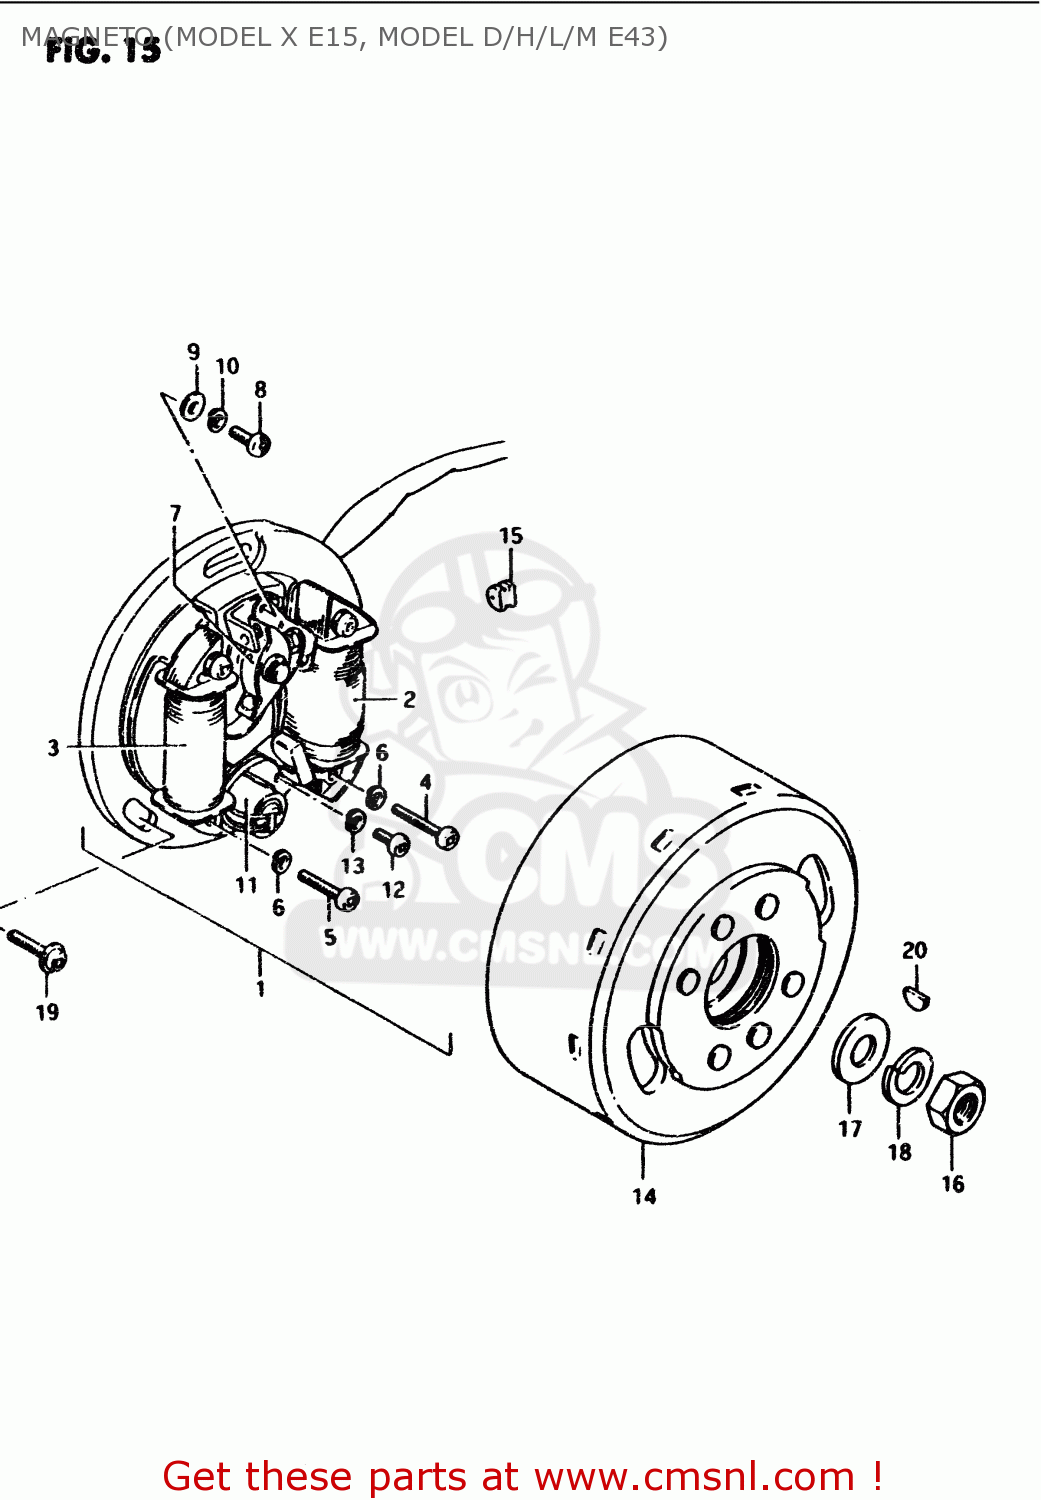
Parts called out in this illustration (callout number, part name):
1	STATOR ASSY
2	COIL,LIGHTING
3	COIL,PRIMARY
4	SCREW 4X25
5	SCREW
6	WASHER,LOCK 4M
7	POINT ASSY,CONTACT
8	SCREW(4X10)
9	WASHER 4MM
10	WASHER,LOCK 4M
11	CONDENSER
12	SCREW
13	LOCK WASHER
14	FLYWHEEL
15	PLUG
16	NUT (10MM)
17	WASHER
18	WASHER,LOCK,10
19	SCREW(5X14)
20	KEY
